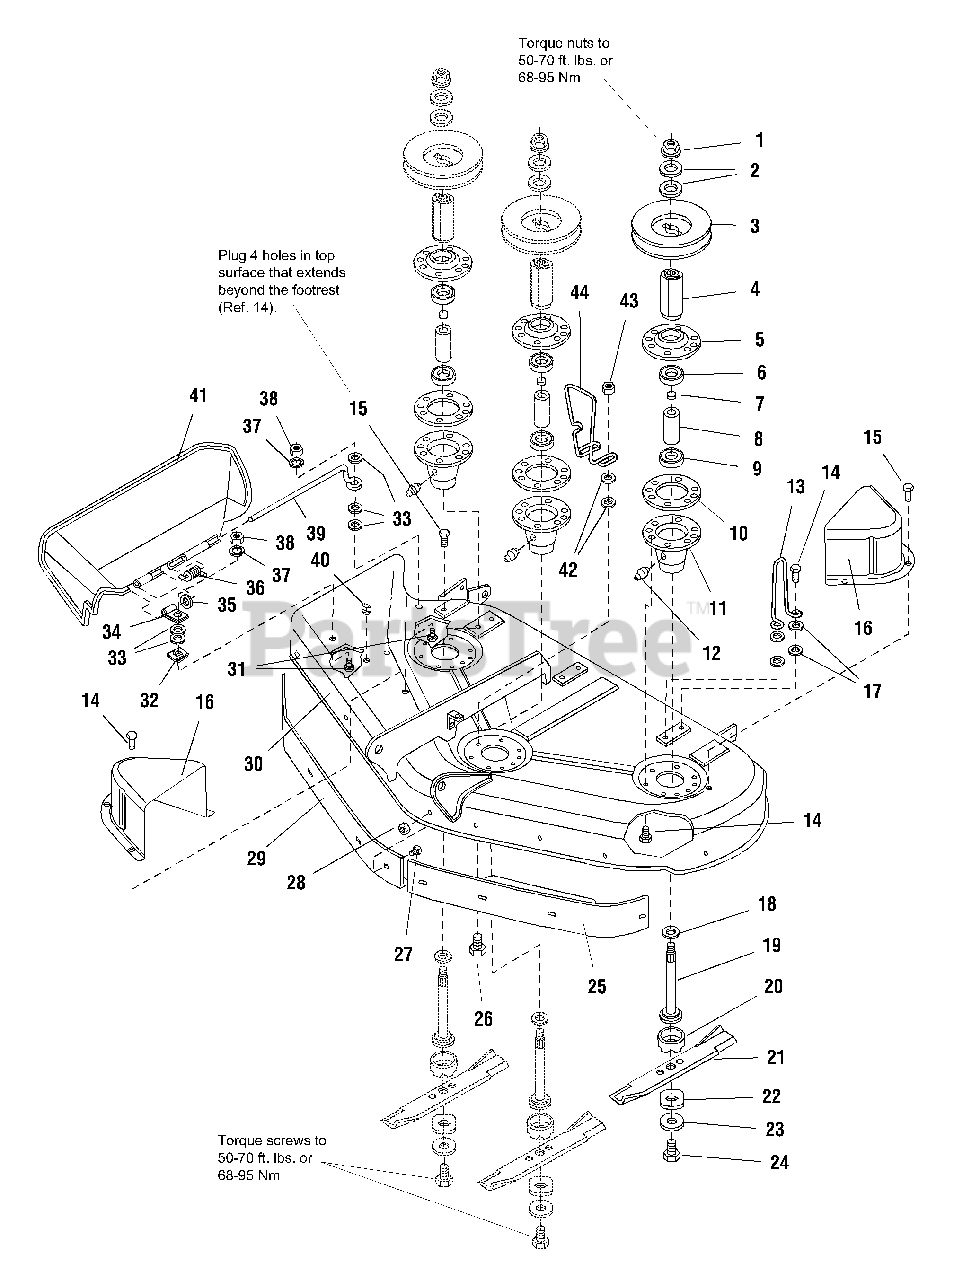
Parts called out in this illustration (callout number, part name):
1	NUT, Hex, Flange, 9/16-8
2	WASHER, Belleville
3	PULLEY, R.H. Arbor, Center Arbor & L.H. Arbor
4	HUB, Adapter (R.H., Center & L.H.)
5	COVER, Arbor Housing
6	BEARING, Upper
7	SPACER, Sleeve, Upper Bearing
8	SPACER, Arbor, Internal
9	BEARING, Lower
10	GASKET, Foam
11	HOUSING ASSEMBLY, Arbor Bottom, w/Lube Fitting
12	FITTING, Grease
13	UP-STOP, 5 1/4 High
14	CAPSCREW, Taptite Hex Washer Hd, 5/16-18 x 1
15	CAPSCREW, Taptite Hex Washer Hd, 5/16-18 x 3/4
16	COVER, Arbor
17	WASHER, 5/16
19	SHAFT, Arbor (R.H., Center & L.H.)
20	SHIELD, Grass, Lower
21	BLADE, Mower, 16-1/8
22	WASHER, Hex
23	WASHER, Spring
24	CAPSCREW, Hex, Hd., 7/16-14 x 1-1/4
25	BAFFLE, Blowout, L.H.
26	CAPSCREW, Taptite Hex Washer Hd, 5/16-18 x 1 1/2
27	CARRIAGE BOLT, 5/16-18 x 3/4
28	NUT, Hex Flange 2-Way Lock 5/16-18
29	BAFFLE, Blowout R.H.
30	HOUSING ASSEMBLY, (Cardinal Red)
31	CARRIAGE BOLT, 1/4-20 x 7/8
32	NUT, Push On
33	WASHER, Plain, 1/4
35	WASHER, Plain, 5/16
36	SPRING, Deflector Retaining
37	LOCKWASHER, 1/4
38	NUT, Hex, 1/4-20, UNC
39	ROD, Deflector, Front
41	DEFLECTOR, Plastic
42	WASHER, 3/8
43	NUT, Hex Flange Whiz Lock, 5/16-18
44	BELT STOP, Center
